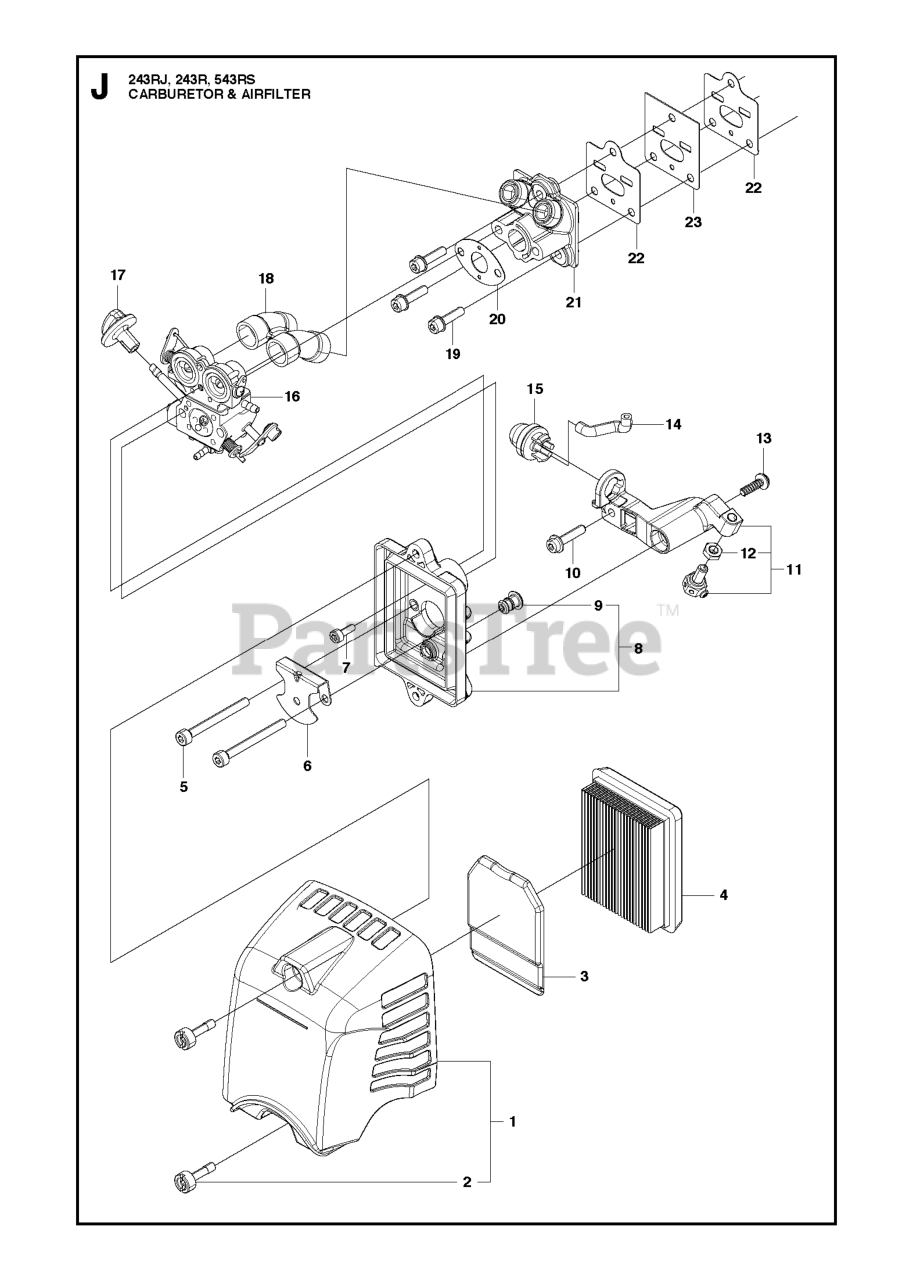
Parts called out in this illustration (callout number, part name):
1	AIR FILTER COVER ASSY GZ40N7
2	TURNING KNOB GZ40N7
2	SCREW
4	ELEMENT
5	BOLT TORX
5	BOLT
7	BOLT M4 X 12 T27
8	HOUSING
10	BOLT TORX
11	BRACKET ASSY
12	NUT,CABLE ADJ(RPLS175181180
14	PIPE L70
14	TUBE
16	CARBURETOR ASSY WTEA-4A
17	KNOB
19	BOLT TORX
19	BOLT, TORX
20	GASKET
21	INSULATOR
22	GASKET
23	PLATE
